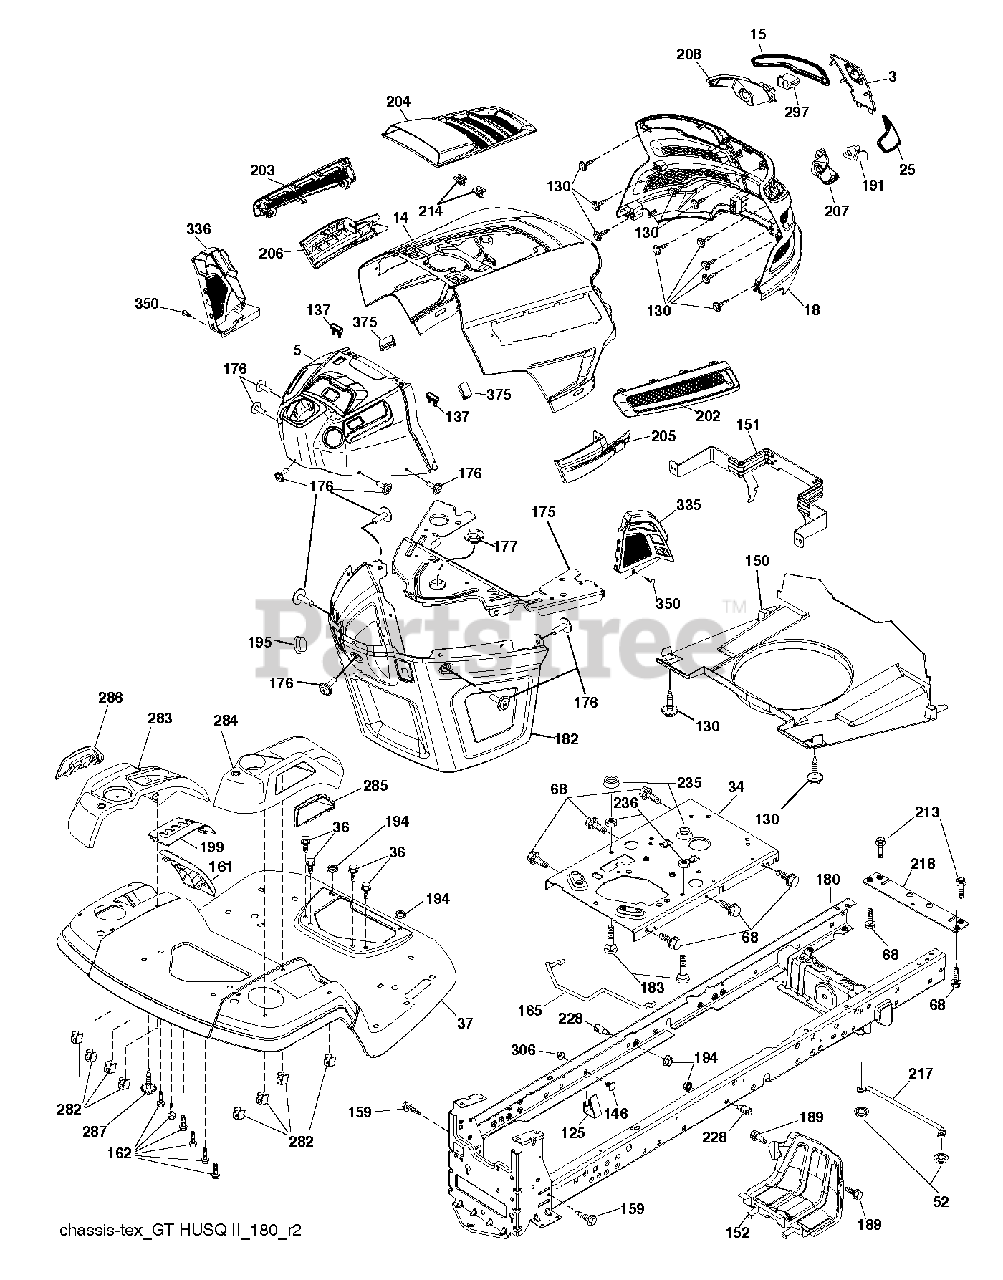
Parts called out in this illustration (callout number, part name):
3	APPLIQUE.SUBASM.GT.HUSQ.II
5	DASH.UPR.GT2.SRV.MIND.PTO
14	HOOD.ASM.HUSQVARNA.GT.TEX.ORAN
15	LENS.HEADLIGHT.LH.GTII.2011
18	GRILLE SUBASM.GT.II.LOW.HDLGHT
25	LENS.HEADLIGHT.RH.GTII.2011
34	PLATE.ENGINE.WELDED.CHASSIS
36	SCREW 5/16"
37	FENDER.TLT.FS.W/CPH.W/FW.668
52	LOCKNUT
68	SCREW LT
125	CLIP.FUEL.LINE
130	SCREW.#10 X 0.750.BOS
137	BUMPER DASH
146	BOLT.RDHD.SHT.SQNK.3/8-16X5/8
150	AIR DUCT.GTV2(1.66"RING HEIGHT
151	BRACKET.PIVOT.HOOD.GT.HUSQ.II
152	SHIELD.BROWNING.PNT.GT.V2
159	SCREW, 3/8-16X3/4
161	WINDOW.FUEL.LT.TEX.GREY
162	SCREW.HI-LO.CONSOLE
165	SUPPORT.TANK.REAR.W/TEX
175	PLATE.CROSSMEMBER.HUSQ
176	SCREW.#10-24X5/8.RN.QU
177	BUSHING, STEERING
180	CHASSIS
182	DASH.LOWER.COMMON.12V.ADAPTOR
183	BOLT.5/16-18X1-1/4 FULL THD
189	SCREW
191	INSERT.REFLECTIVE.RH.HUSQ.GTII
194	NUT LOCK HEX FLANGE 5/16-18
195	PLUG.HOLE.DASH.LOWER.12V.BLK
199	PLATE.DECK.LIFT.HUSQ.LT
202	VENT.SIDE.RH.GT.HUSQ.II.
203	VENT.SIDE.LH.GT.HUSQ.II.498
204	VENT.TOP.HUSQ.GT2
205	SIDE.TRIM.RH.GT.HUSQ.II
206	SIDE.TRIM.LH.GT.HUSQ.II.GRAY
207	HEADLIGHT.CUP.BEZEL.HUS.GT2.RH
208	HEADLIGHT.CUP.BEZEL.HUS.GT2.LH
213	BOLT
214	CLIP.RETAINER.TINNER.
217	ROD.PIVOT.HOOD
218	X-PIECE.HOOD.STOP.NON/
228	STUD.FASTNER.W/ANTI-ROTATE
235	SPACER FENDER
236	NUT.CENTERLOCK.5/16-
282	CLIP.RETAINER.CONSOLE.LT.HUSQ
283	CONSOLE.ASM.LFT.RSF.HUSQ.LT
284	CONCOLE.CNTRL.PDL.HUSQ.LT.498
285	CONSOLE INSERT RH
286	CONSOLE.INSRT.LH.HUSQ.LT.BLACK
287	SCREW 1/4X20
297	INSERT.REFLECTIVE.LH.HUSQ.GTII
306	NUT LOCK FLG 3/8-16 UNC
335	COVER.LOWER.DASH.RH.BLACK
336	COVER-LH.LOWER.DASH.GT2.BLACK
350	CLIP.X-MAS.TREE
375	BUMPER CLIP-ON. DASH 1"
